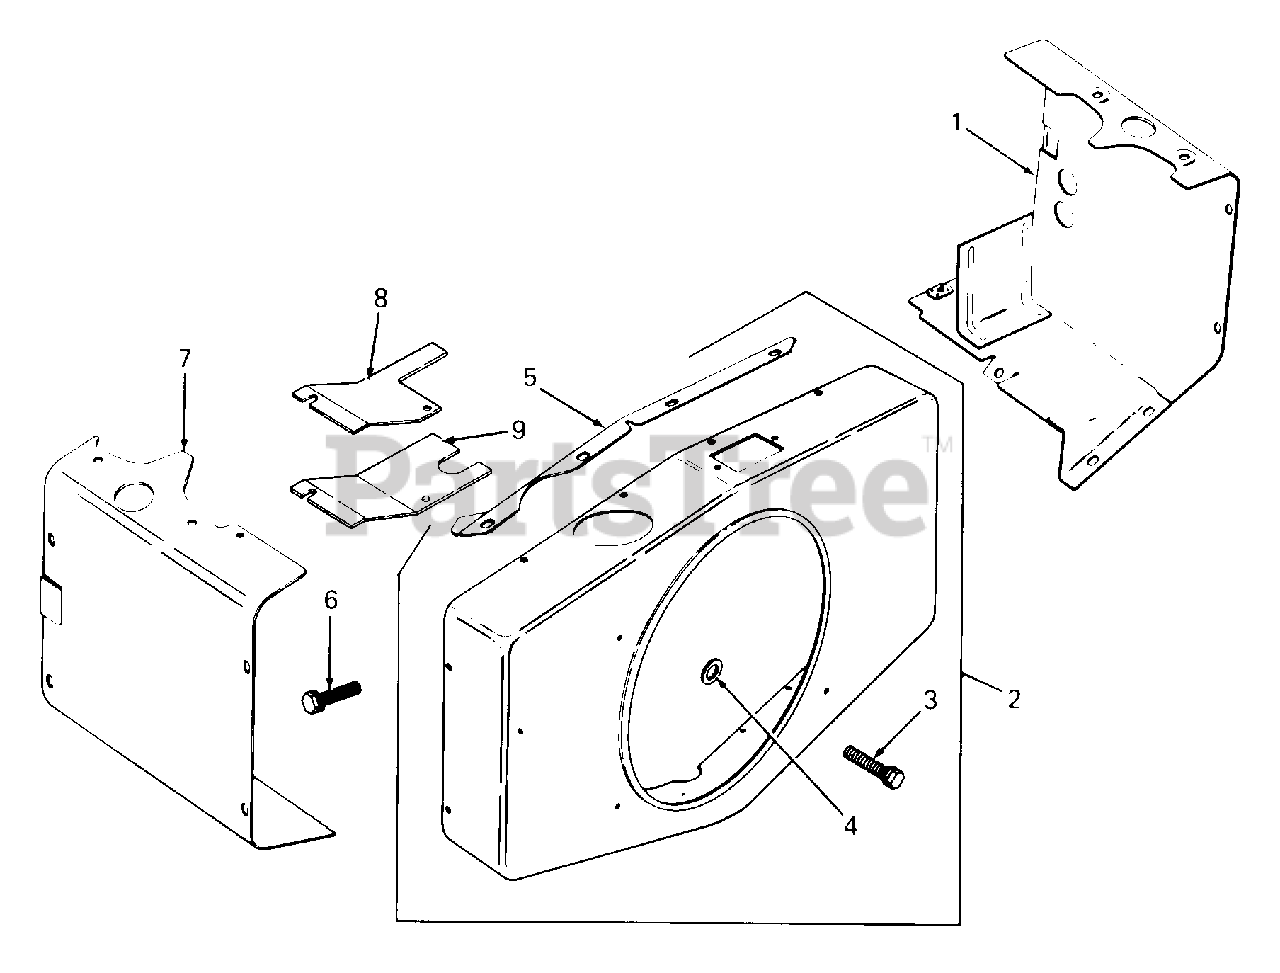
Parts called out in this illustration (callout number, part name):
1	Baffle, #1 Cylinder Head
2	Kit, Blower Housing
3	Screw, Self Tap, 1/4-20 X .62 Lg
4	Washer, Flat, 1/4
5	Support, Upper Housing
6	Screw, Hex Wash Hd, 1/4-20 X .43 Lg
7	Baffle, #2 Cylinder Head
8	Baffle, #2 Cylinder Top
9	Baffle, Pump
